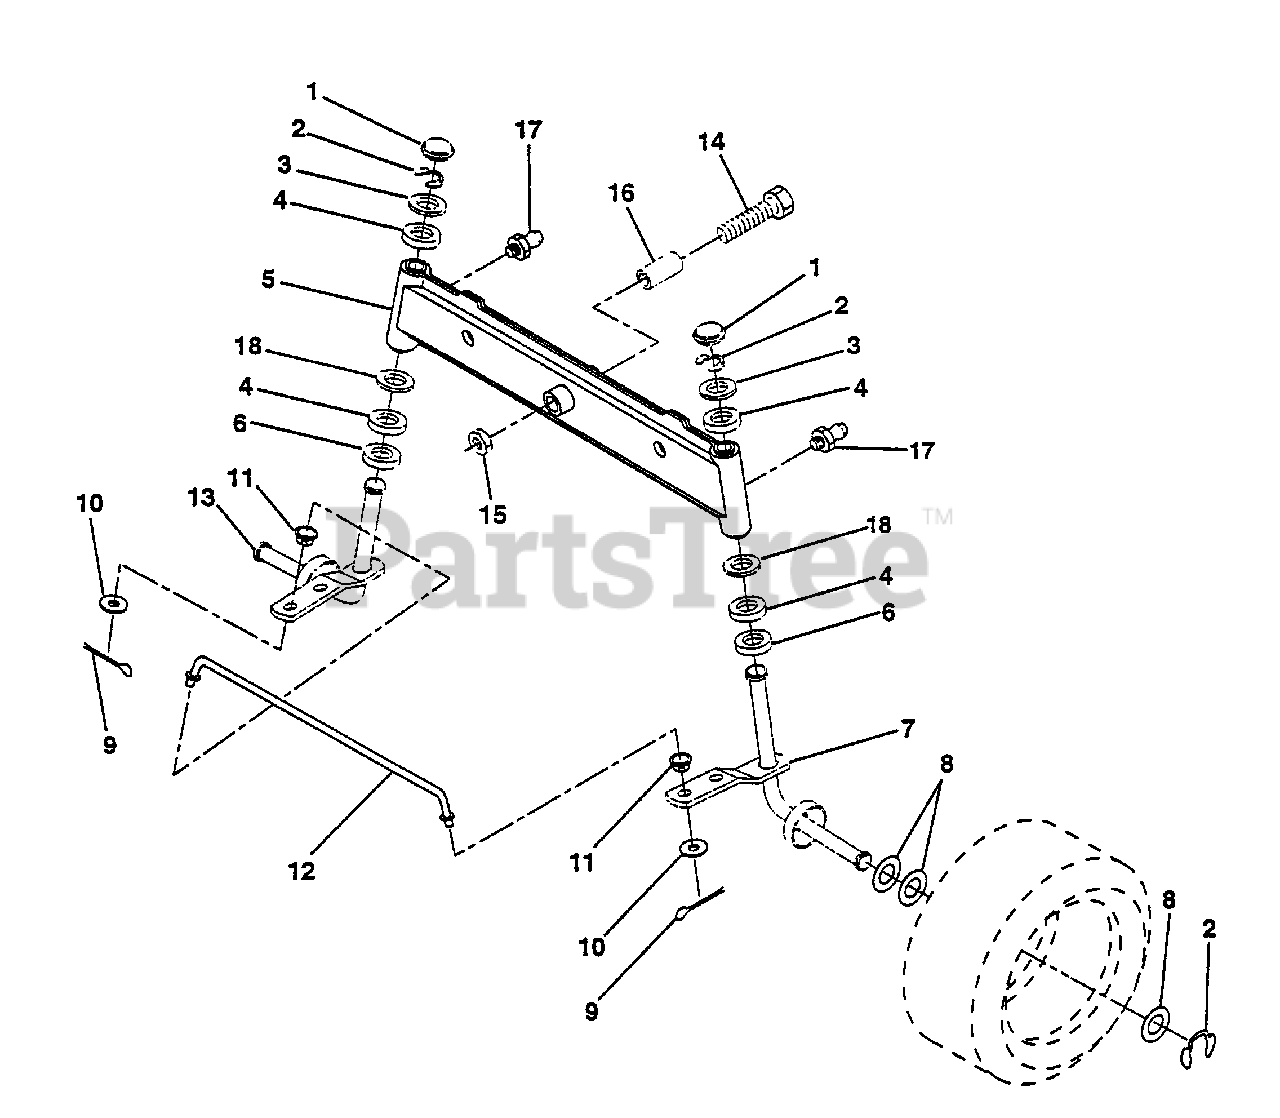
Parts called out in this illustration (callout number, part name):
1	Cap, Spindle
2	Ring, Clip
3	Washer 25/32 x 1-5/8 x 16 Gauge
4	Bearing
5	Axle, Front
6	Bearing, Thrust
7	Spindle Assembly, R.H.
8	Washer 25/32 x 1-1/4 x 16 Gauge
9	Pin, Cotter 1/8 x 3/4
10	Washer 13/32 x 13/16 x 16 Gauge
12	Tie Rod
13	Spindle Assembly, LH.
14	Bolt Hex 5/8-11 Unc x 3-1/2
15	Nut Lock Flange 5/8-11 Unc
16	Spacer Bearing
17	Fitting Grease
18	Washer 27/32 x 1-1/4 x 16 Ga.
